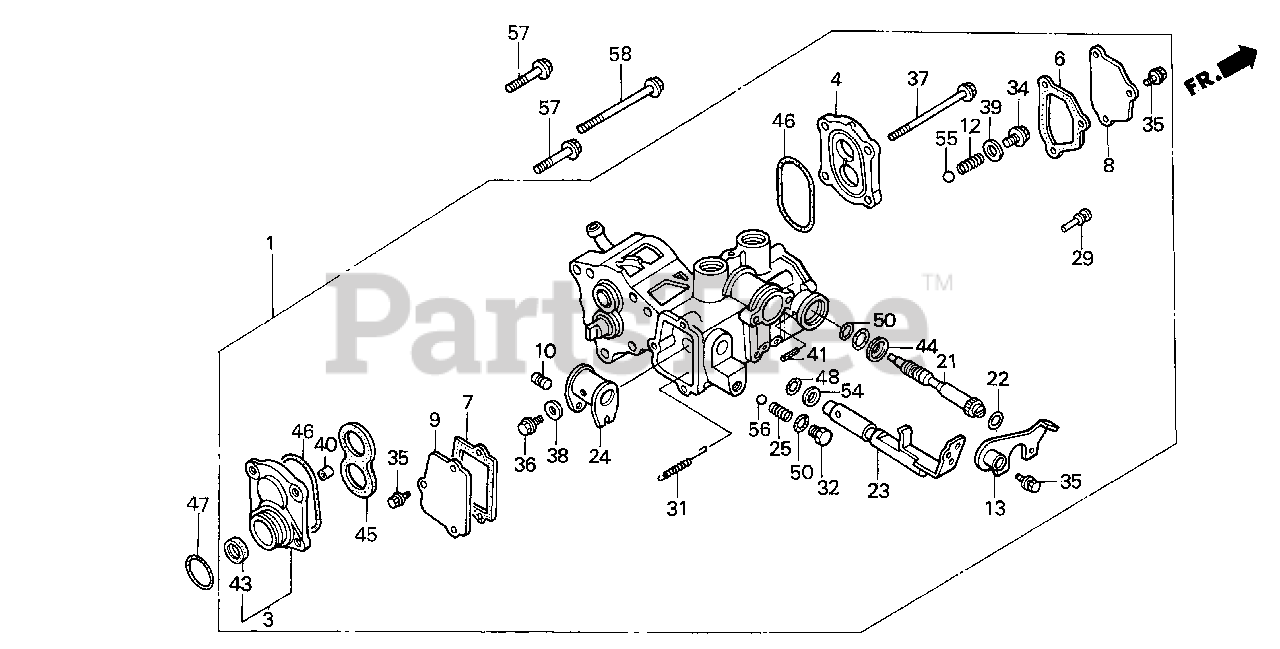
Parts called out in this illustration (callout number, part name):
1	PUMP & VALVE ASSY.
3	COVER, FR. PUMP
4	COVER, RR.
6	GASKET A, VALVE FRAME
7	GASKET B, VALVE FRAME
8	COVER A, VALVE FRAME
9	COVER B, VALVE FRAME
10	PIN, MANUAL VALVE
12	SPRING, ROTARY BALL SET
13	PLATE, ROTARY STOPPER
21	VALVE, DRAIN CONTROL
22	MARK, HYDRAULIC ADJUSTING KNOB (ENGLISH)
23	SHAFT, HYDRAULIC CONTROL
24	FORK, SPOOL VALVE
25	SPRING, BALL SET (A)
31	SPRING, MANUAL VALVE
32	PLUG (10X8.5)
34	BOLT, FLANGE (8X8)
35	BOLT, FLANGE (6X14)
36	BOLT, SPECIAL (6X20)
37	BOLT, FLANGE (6X85)
38	WASHER, CONICAL SPRING (8MM)
39	WASHER, SEAL
40	PIN, DOWEL (8X10)
41	PIN, SPRING (4X20)
43	OIL SEAL (16X30X7) (NOK)
44	DUST SEAL (12X22X4)
45	SEAL, PLUNGER (NOK)
46	O-RING (53.8X3.1)
47	O-RING (37.5X2)
48	O-RING (11.8X2.4)
50	O-RING (7.8X1.9)
54	RING, BACK-UP (12MM)
55	BALL, STEEL (8)
56	BALL, STEEL (11)
57	BOLT, FLANGE (8X35)
58	BOLT, FLANGE (8X75)
